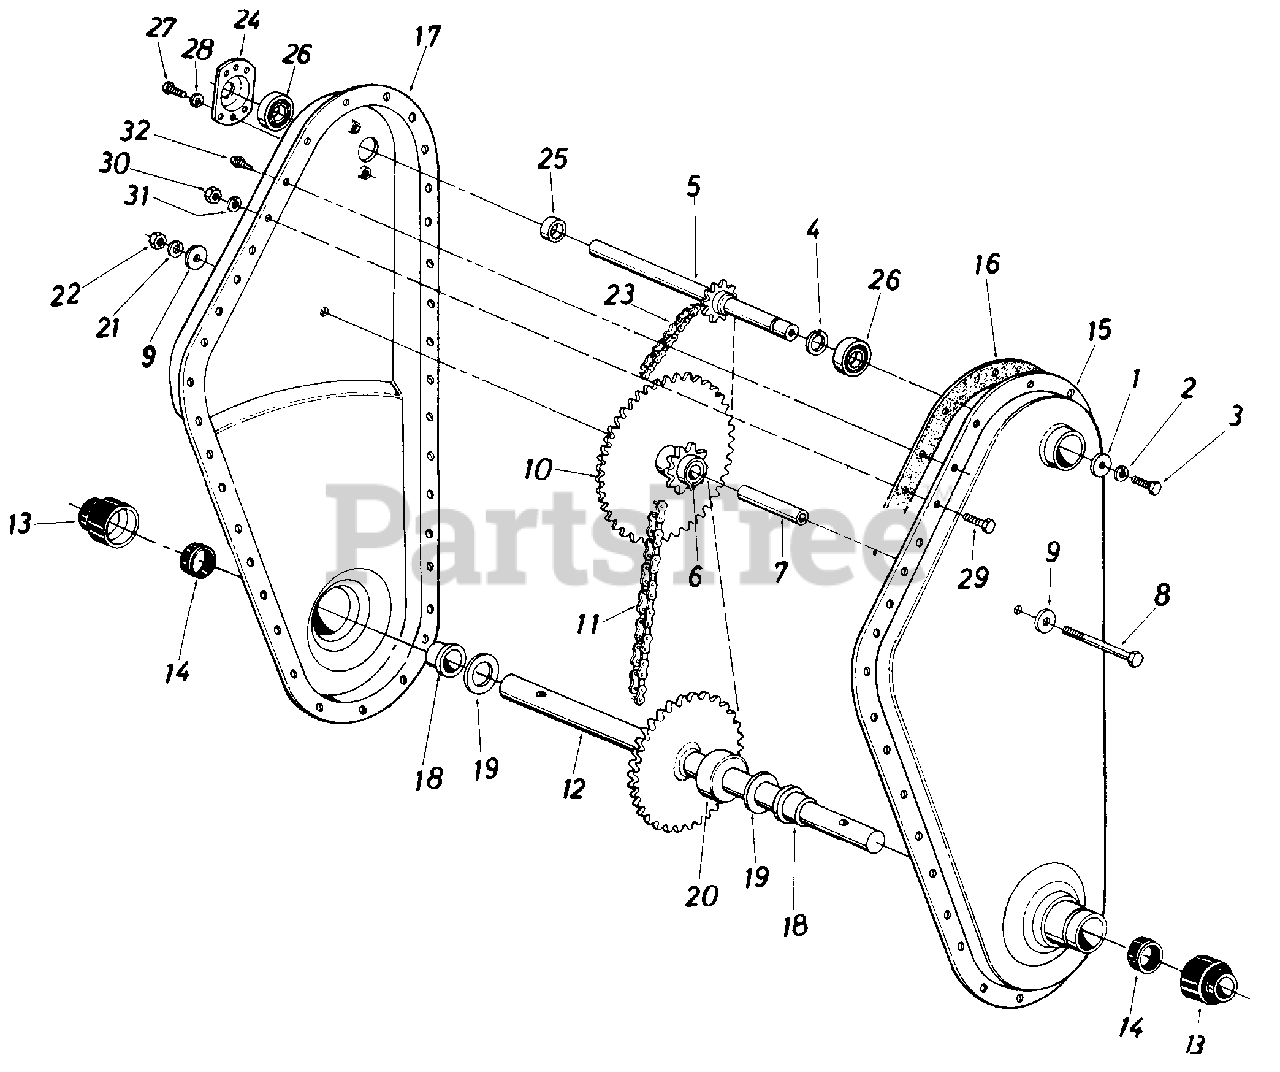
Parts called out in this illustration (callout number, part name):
1	Fl-Wash. 1/4" I.D. x .93" O.D. x .1 20
2	L-Wash. 1/4" I.D.*
3	Hex Bolt 1/4-28 x .62" Lg. w/Patch
4	External Snap Ring-5/8" Dia.
5	Input Shaft Ass'y.
6	Bearing 5/8" I.D. x 3/4" O.D. x 1.860" Lg.
7	Sprocket Hub Tubing 3/8" I.D. x 5/8" O.D. x 1.90
8	Hex Bolt 3/8-24 x 2.75" Lg.*
9	Fl-Wash. 3/8" I.D. x 1.25" O.D. x .10
10	Sprocket Ass'y.
11	#50 Chain 5/8" Pitch x 46 Links Endless
12	Tine Shaft Ass'y.
13	Dust Cup
14	Seal Ring Single Lip, Springless
19	Fl-Thrust Wash. 1.0" I.D. x .03 Thk.
20	Step Spacer
21	L-Wash. 3/8" I.D.
22	Hex Nut 3/8-24 Thd.
23	#35 Chain 3/8" Pitch x 52 Links Endless
24	Bearing Housing 1.38" I.D.
25	Spacer
26	Ball Bearing .625" I.D. x 1.38" O,D. x .437
27	Hex Wash. SF-Tap Scr. 1/4-20 x.50" Lg.
28	L-Wash. 1/4" I.D.
29	Hex Bolt 5/16-18 x .75" Lg.
30	Hex Nut 5/16-18 Thd.
31	L-Wash. 5/16" I.D.
32	Hex Wash. SF-Tap Scr. 1/4-20 x.50" Lg.
